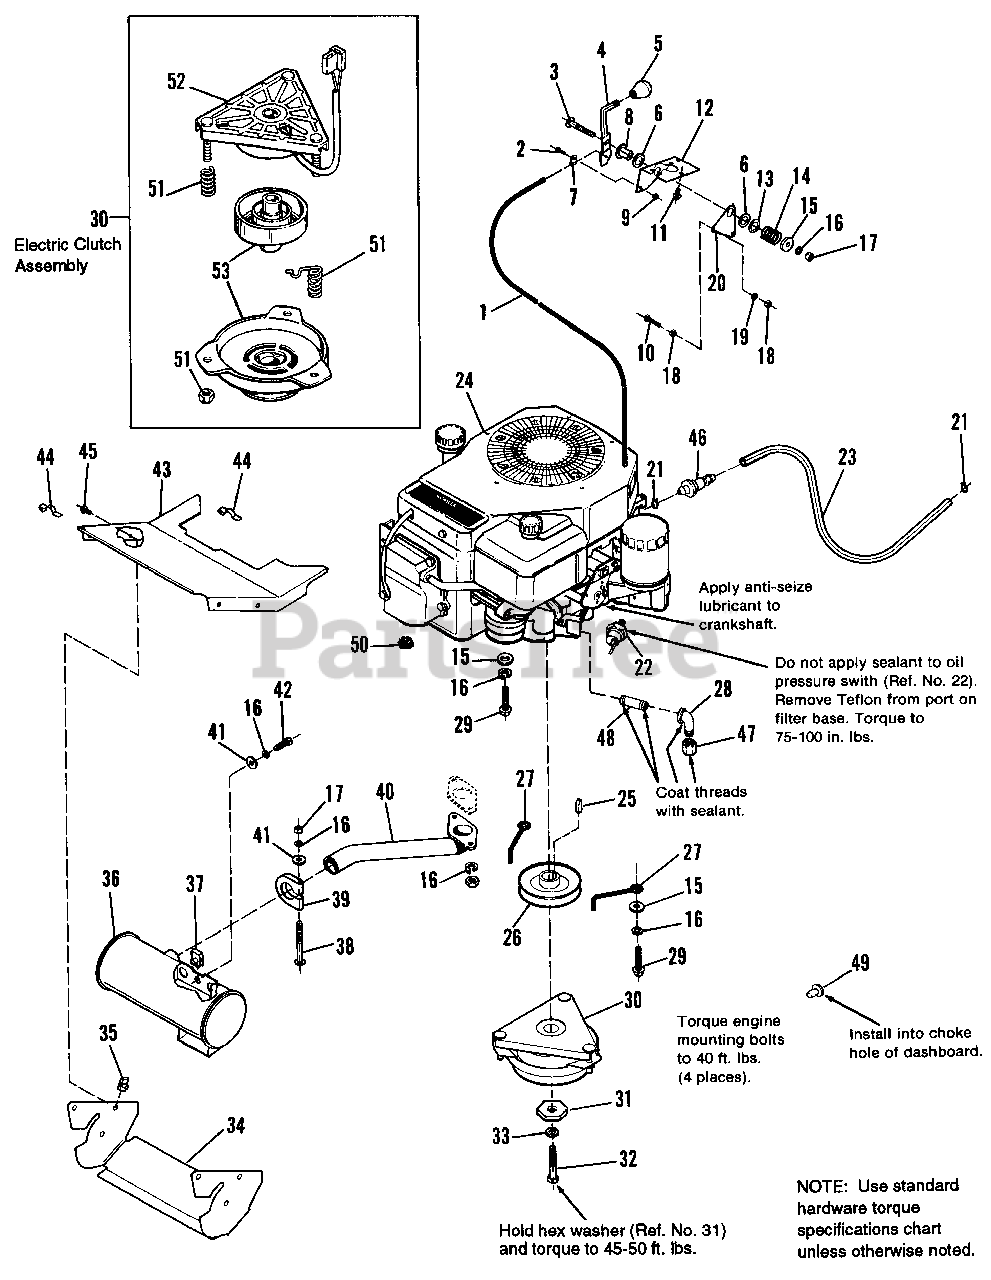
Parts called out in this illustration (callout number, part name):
1	CABLE, Throttle
2	SCREW, Trusshead, 10-32 x 1/2
3	CARRIAGE BOLT, 5/16-18 x 1-3/4
4	HANDLE, Throttle
5	KNOB, Throttle
6	WASHER, Nylon
7	CLIP, Bowden Wire
9	NUT ASSY., 10-32
10	CAPSCREW, Hex, 1/4-20 x 1-1/4
11	SCREW, Plastite, 1/4-20 x 5/8
12	BRACKET, Throttle Mounting
15	WASHER, Plain, 5/16
16	LOCKWASHER, 5/16
17	NUT, Full, Hex, 5/16-18
18	NUT, Full, Hex, 1/4-20
19	LOCKWASHER, 1/4
20	PLATE, Spring
21	CLAMP, Hose
22	SWITCH, Oil Pressure
23	HOSE, Fuel, 45-1/2" Long
24	ENGINE, (Kohler)
25	KEY, Hi-Pro
26	PULLEY ASSY. (12.5 Only)
26	PULLEY ASSY. (14 HP Hydro Only)
28	STREET ELBOW, 3/8 Pipe
29	SCREW, Taptite, M8-1-1/4 x 30 mm
30	ELECTRIC CLUTCH (Incl. Ref. Nos. 52-55)
31	WASHER, Hex
32	CAPSCREW, M10-1-1/2 x 60 mm
33	LOCKWASHER, 7/16
34	DUCT, Lower Muffler
35	NUT, Pal, 1/4-20
36	MUFFLER ASSY.
37	NUT, Pal, 5/16-18
38	CARRIAGE BOLT, 5/16-18 x 2-3/4
39	CLAMP, Muffler
40	PIPE, Exhaust
41	WASHER, Plain, 5/16
42	CAPSCREW, Hex, 5/16-18 x 1
43	DUCT, Top, Muffler
44	CLIP
45	SCREW, Flange Whiz, 1/4-20 x 5/8
46	FUEL FILTER
48	PIPE NIPPLE, 3/8 x 2
49	FASTENER, Panel
50	LOCKWASHER, External Tooth, 5/16
51	SPRING & NUT KIT
52	FIELD ASSY., Clutch
53	ROTOR & ARMATURE ASSY.
